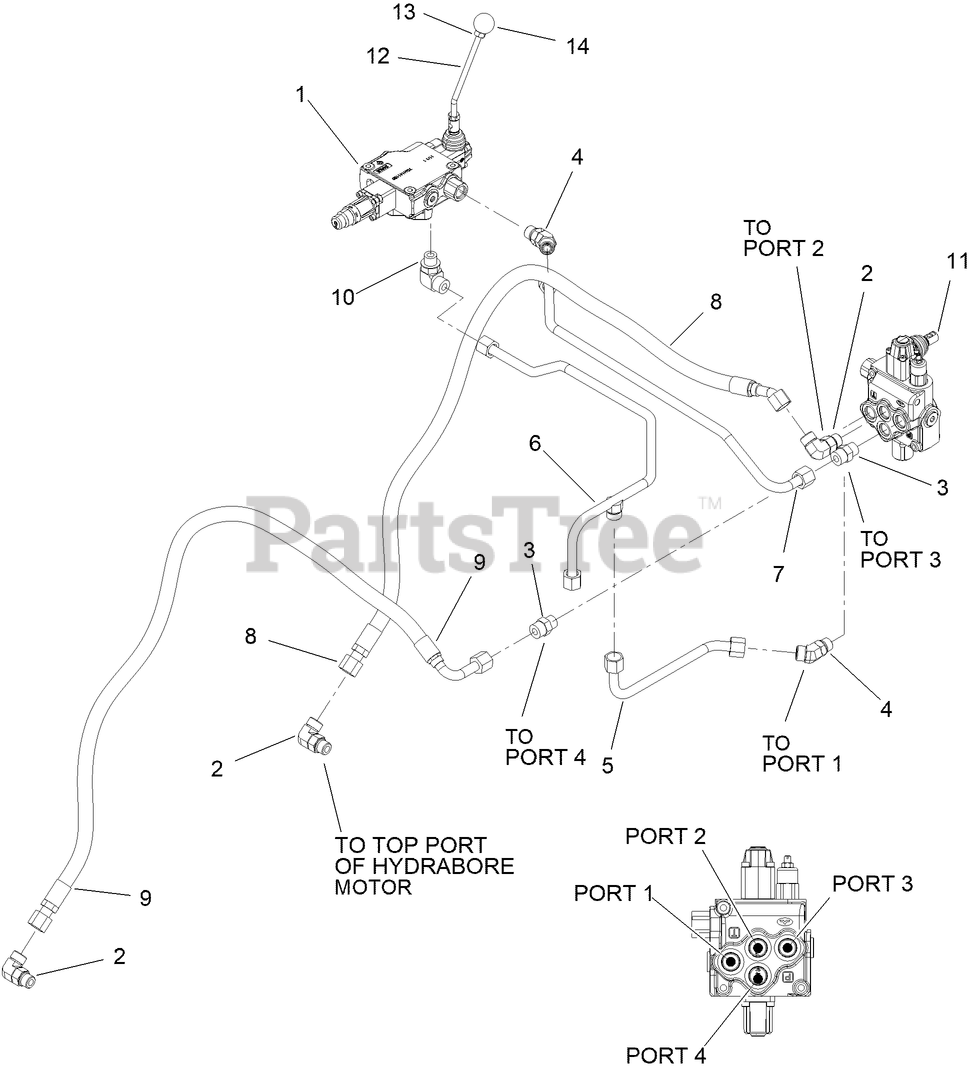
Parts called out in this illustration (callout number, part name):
1	VALVE-TRENCHER
2	CONNECTOR (10S-10O90)
3	CONNECTOR (10S-10O)
4	CONNECTOR (10S-10O45)
5	HARDLINE (-10 HYDRABORER TO RETURN)
6	HARDLINE (-10 TRENCHER TO RETURN)
7	HARDLINE (-10 HYDRABORER TO TRENCHER)
8	HOSE (10OFX45-53"-3000)
9	HOSE (10OFX90L-54"-3000)
10	CONNECTOR (10S-10O90)
11	HYDRO VALVE ASM
12	LEVER-TRENCHER
13	NUT
14	KNOB-ROUND
